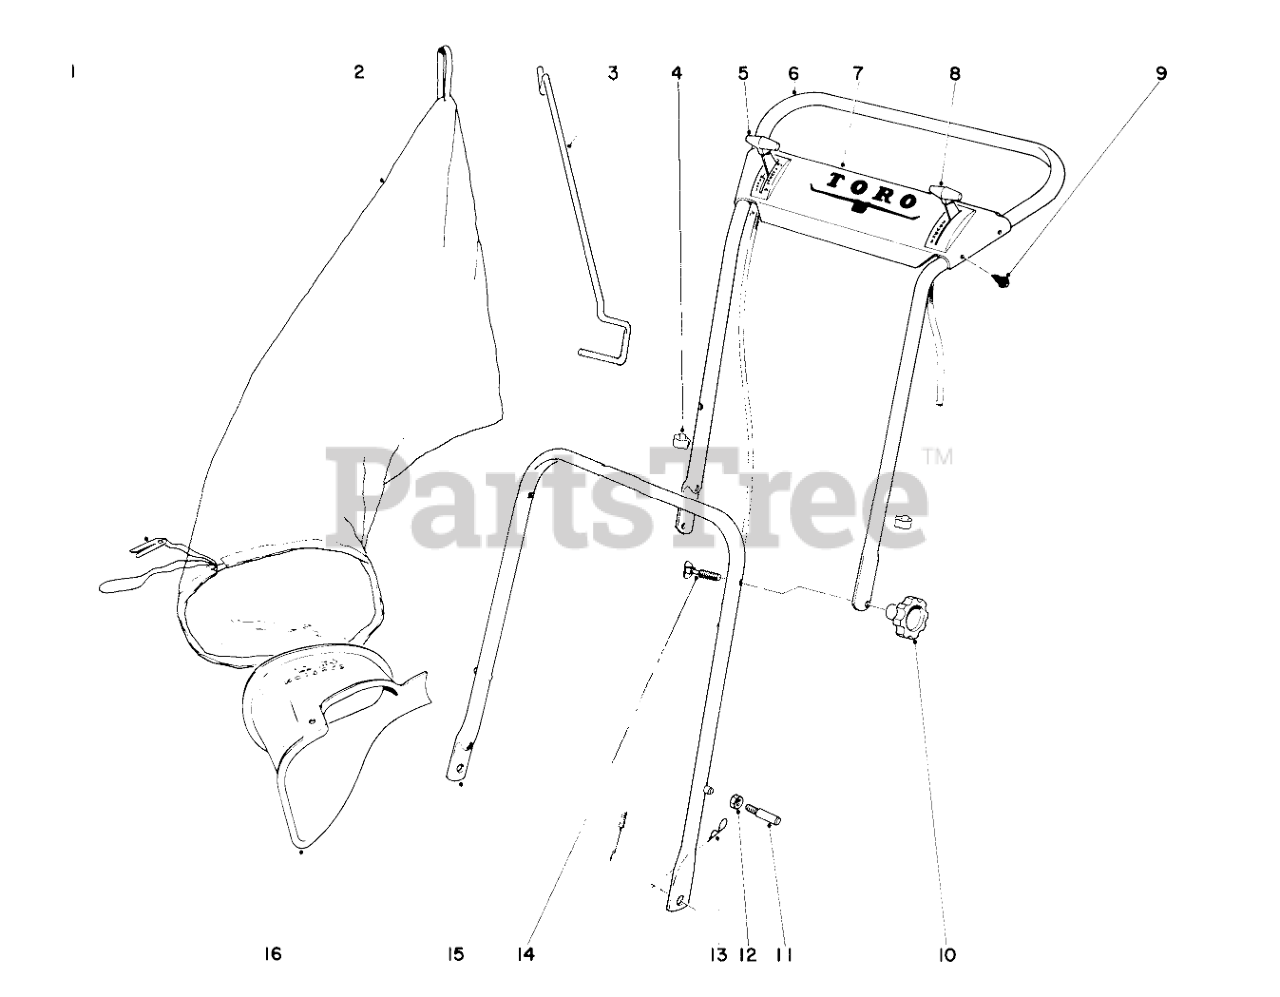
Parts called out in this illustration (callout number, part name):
1	BAG CORD FASTENER
2	Grass Bag Kit (2 Bags) (Incl. Ref. No. 1)
3	Bag Hanger Rod
4	CONTROL WIRE CLIP
5	Throttle Control
6	Upper Handle
7	Plate, Escutcheon
8	Traction Control
9	SCREW-HWHTF
10	Handle Release Knob
11	Handle Pin
12	Nut
13	PIN-COTTER, HAIR
14	HANDLE SCREW
15	Lower Handle
16	BAG ATTACHMENT
